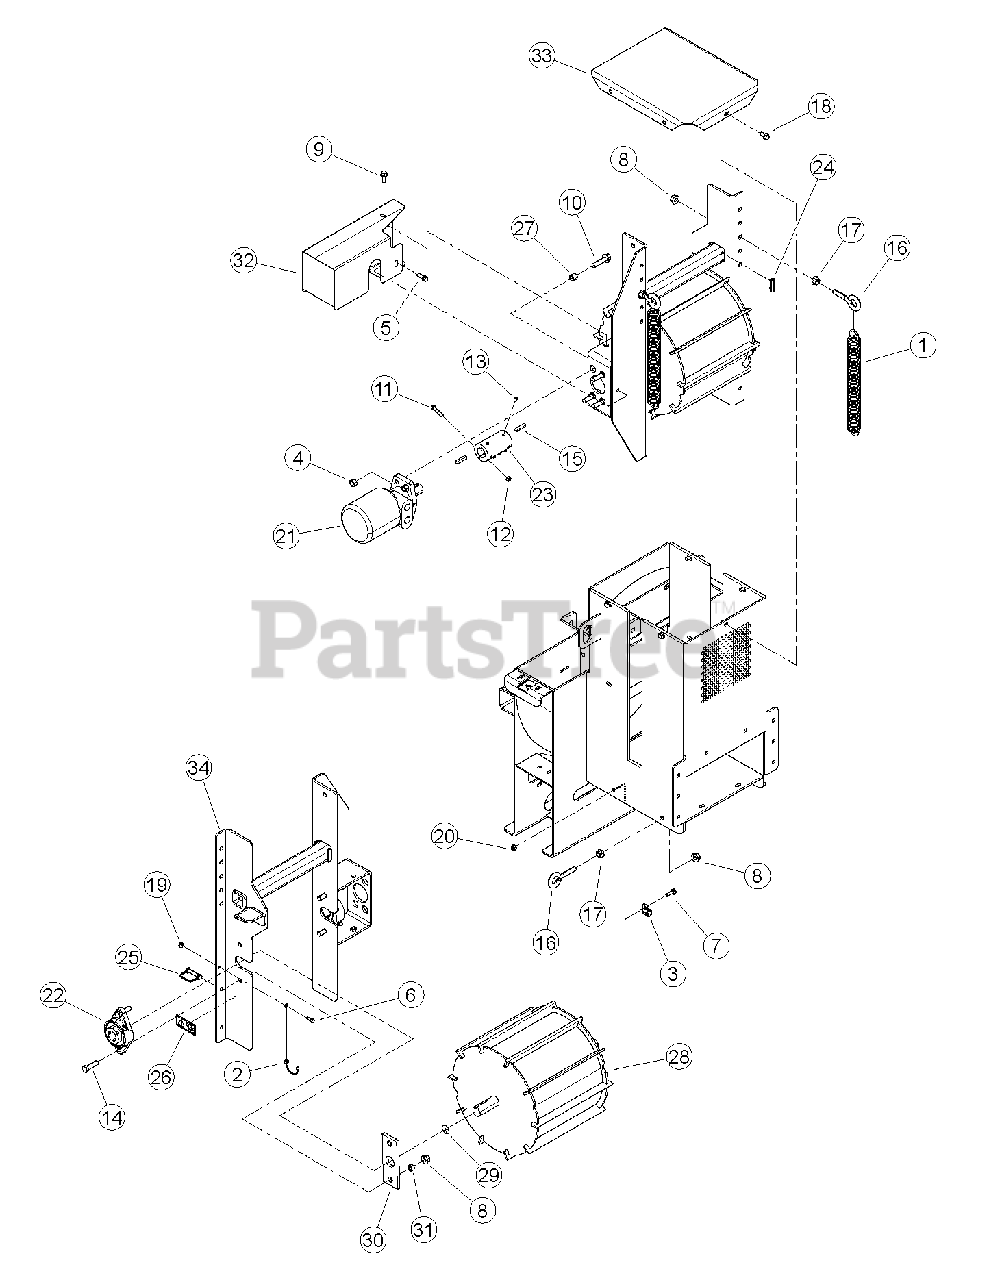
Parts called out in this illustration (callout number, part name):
1	SPRING, EXTENSION
2	LANYARD, NYLON
3	CLAMP, 9/16 COATED
4	NUT, 1/2" CENTERLOCK GRB ZP
5	SCREW,3/8-16 X 1 T23 THD CUTT HWH MAGNI 565 SILVER
6	BOLT, 1/4-20 X 3/4 HWH GR5 CZP
7	BOLT, 5/16 X 1 FLANGE NC
8	NUT, 1/2-13 NYLOCK FLANGE
9	BOLT, 3/8 X 1 FLANGE NC
10	BOLT, 1/2-13 X 2 HWH GR5 CZP
11	BOLT, 5/16 X 1-1/2 GR5 HEX CPS ZP
12	NUT, 5/16" NE NYLOCK ZP
13	SET SCREW, 3/8 X 1/2 CUP PT SKT
14	BOLT, 1/2 X 1 3/4 GR5 HCPS NC ZP
15	KEY, 5/16 X 1-1/2 SQUARE
16	EYEBOLT, 1/2 X 2" ZP
17	NUT, 1/2 SPIRAL LOCK NC ZP
18	BOLT, 3/8 X 3/4" SERRATED FLANGE
19	NUT, 1/4-20 NYLOCK-FLANGE
20	NUT, 5/16-18 NYLOCK-FLANGE
21	MOTOR, 45 CU IN HYDRAULIC
22	BEARING, 1-1/4" DIA 2 BOLT FLANGE
23	COUPLER, 1-1/4 SHAFT
24	WEAR PAD, STD.SPRING HD FRONT
25	PIN, SNAP 3/8 X 1-1/2 USABLE LGH
26	DECAL, CRUSHING ISO
27	SPACER,0.75 X 0.620
28	ASSEMBLY, 6" FEED ROLLER SERVICE
29	DECAL, ROTATING SHAFT
30	BEARING, SLIDE
31	SPACER, .75 OD X .5 ID X .37
32	WELDMENT, MOTOR COVER
33	WELDMENT, TOP ROLLER COVER
34	WELDMENT, ROLLER SLIDE
